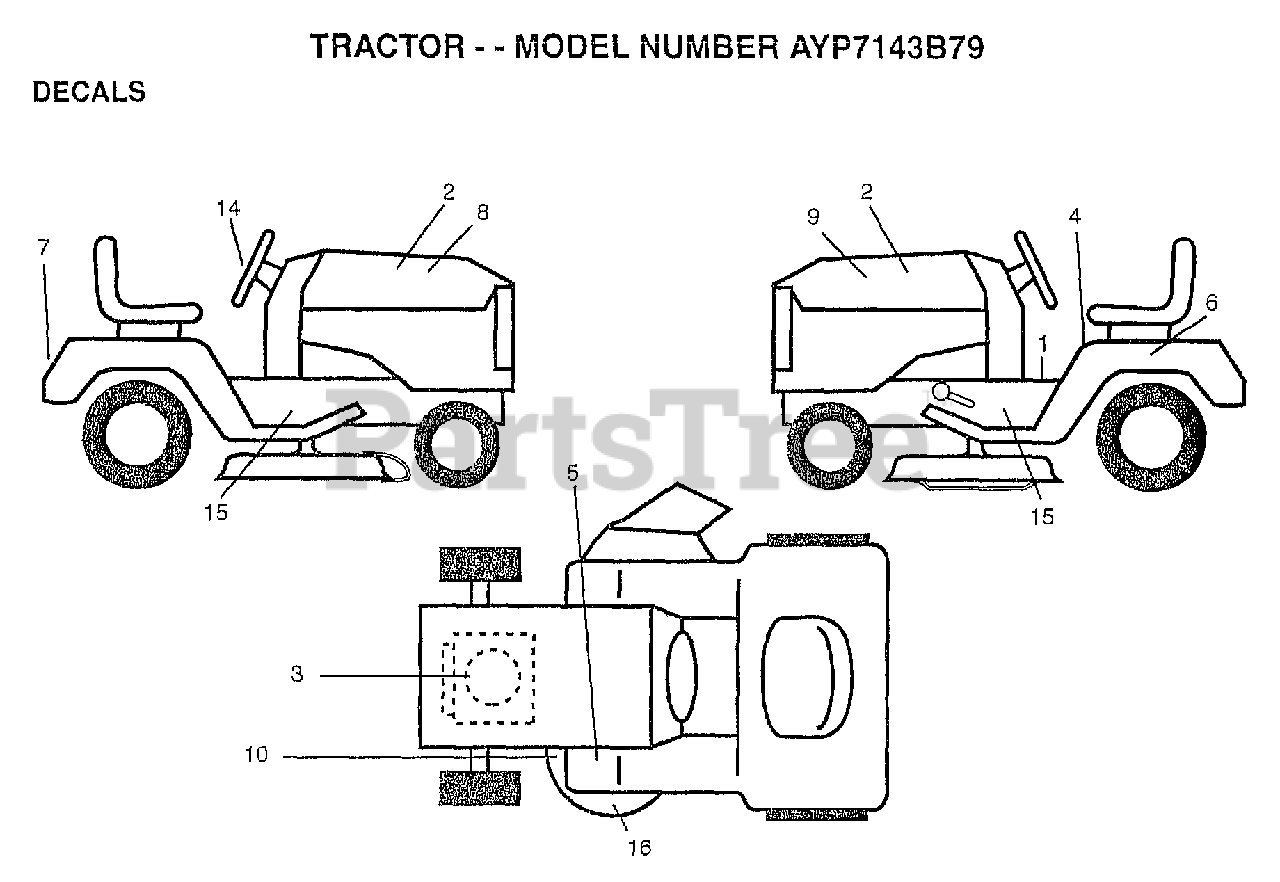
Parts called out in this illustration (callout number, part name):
1	"DECAL DASH,OPER."
2	DECAL.INS.HD.14.5
3	DECAL, ENGINE
4	"DECAL DANGER,FEND"
6	DECAL.BATRY.3-3908
8	DECAL.HD.RH.WIZAR
9	DECAL.HD.LH.WIZAR
10	DECAL
14	DECAL.INS.STRG.WL
15	DECAL CHASSIS WIZ
16	DECAL DECK WIZ +
